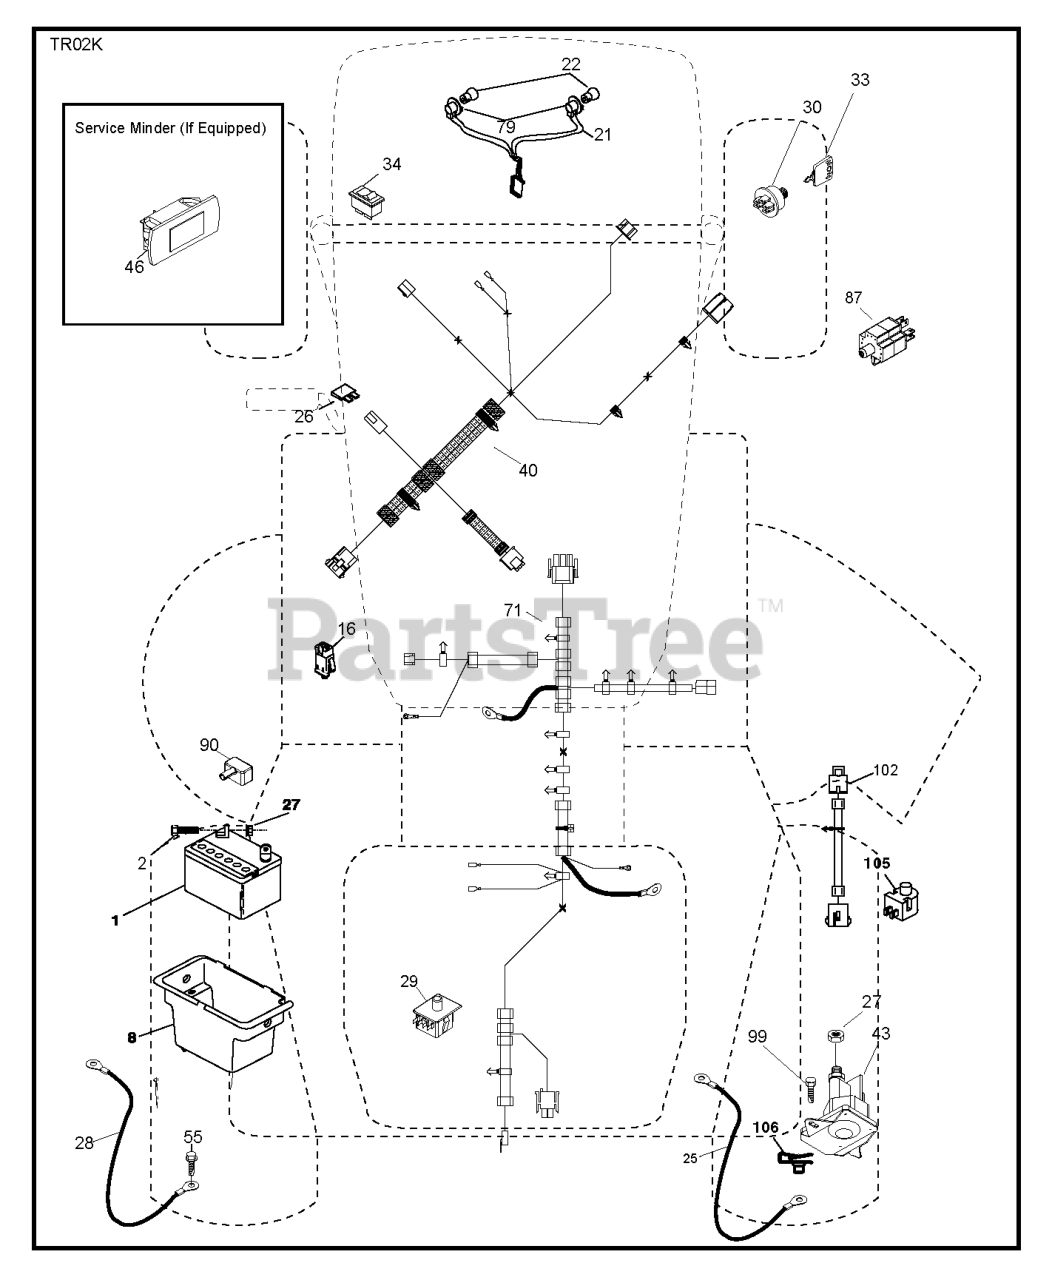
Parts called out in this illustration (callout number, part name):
1	REPL BY 532 12 38-99
2	Bolt, Hex Hed. 1/4-20 UNC x 3/4 (AYP part number)
8	BOX.BATTERY.MNT.REAR.L
16	SWITCH INTERLOOK PUSH-IN
21	HARNESS.LIGHT W/4152J BULBS
22	Bulb Light #1156 (AYP part number)
25	CABLE.BATT.RED.8GA.17
26	FUSE 20AMP
27	Nut Keps Hex 1/4 - 20 UNC (AYP part number)
28	CABLE.GROUND.REAR.BATTERY.8G
29	SWITCH.SEAT.DP W/RAMPS
30	SWITCH.IGN.DELTA.W.LGH.ROS
33	KEY.CHAIN.BLISTER.PACK.GEN.INT
34	Switch Light Blk Blk Red (AYP part number)
40	HARNESS.TEX.DASH.MAN.REAR BATT
43	SOLENOID.STARTER.BRASS.PLUNGER
46	GUAGE.SRVCMNDR.HRMTR.
55	SCREW 5/16"
71	HARNESS.CHASSIS.RRBATT.RDYSTRT
79	BULB HOLDER ASM.
87	SWITCH.INTRLCK.CLUTCH.
90	COVER.TERMINAL.BATTERY
99	SCREW HEXWSHR 1/4-20X3/4
102	HARNESS.PIGTAIL.VARIATOR.SD
105	REVERSE SWITCH
106	1/4-20 U NUT
